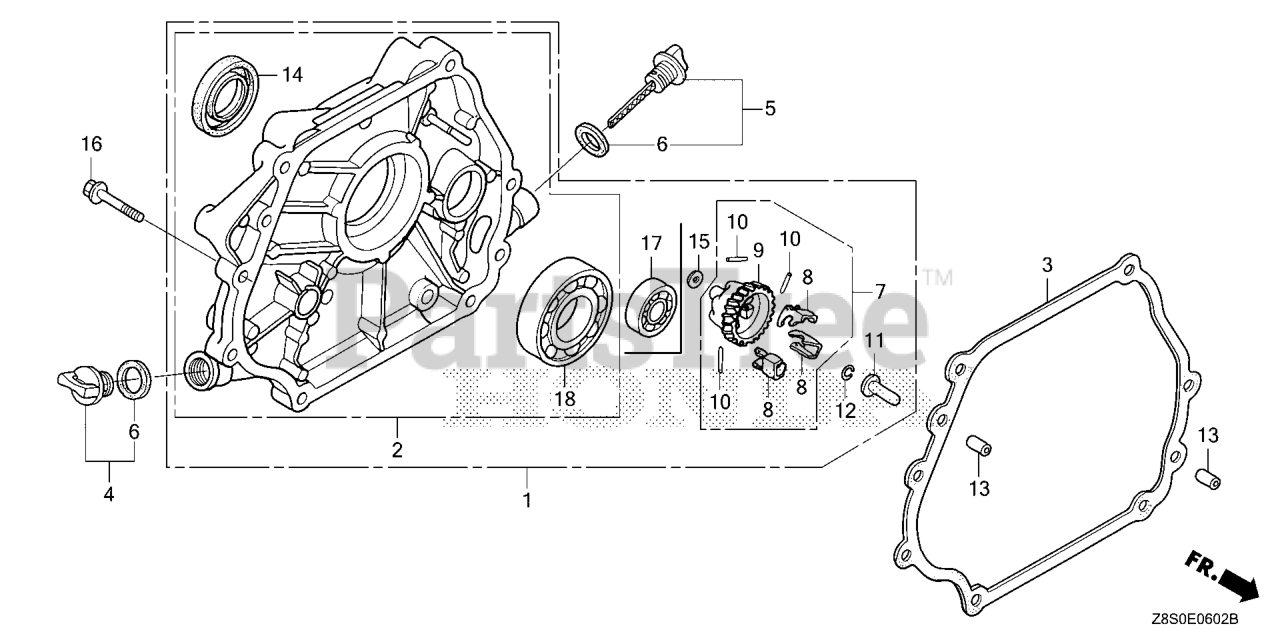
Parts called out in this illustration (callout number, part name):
1	COVER ASSY., CRANKCASE
3	GASKET, CASE COVER
4	CAP ASSY., OIL FILLER
5	CAP ASSY., OIL FILLER
6	GASKET, OIL FILLER CAP
7	GOVERNOR ASSY.
8	WEIGHT, GOVERNOR
9	HOLDER, GOVERNOR WEIGHT
10	PIN, GOVERNOR WEIGHT
11	SLIDER, GOVERNOR
12	CLIP, GOVERNOR HOLDER
13	PIN, DOWEL (8X12)
14	OIL SEAL (30X46X8) (NOK ASIA)
15	WASHER, PLAIN (6MM)
16	BOLT, FLANGE (8X35)
17	BEARING, RADIAL BALL (6202)
18	BEARING, RADIAL BALL (6206)
